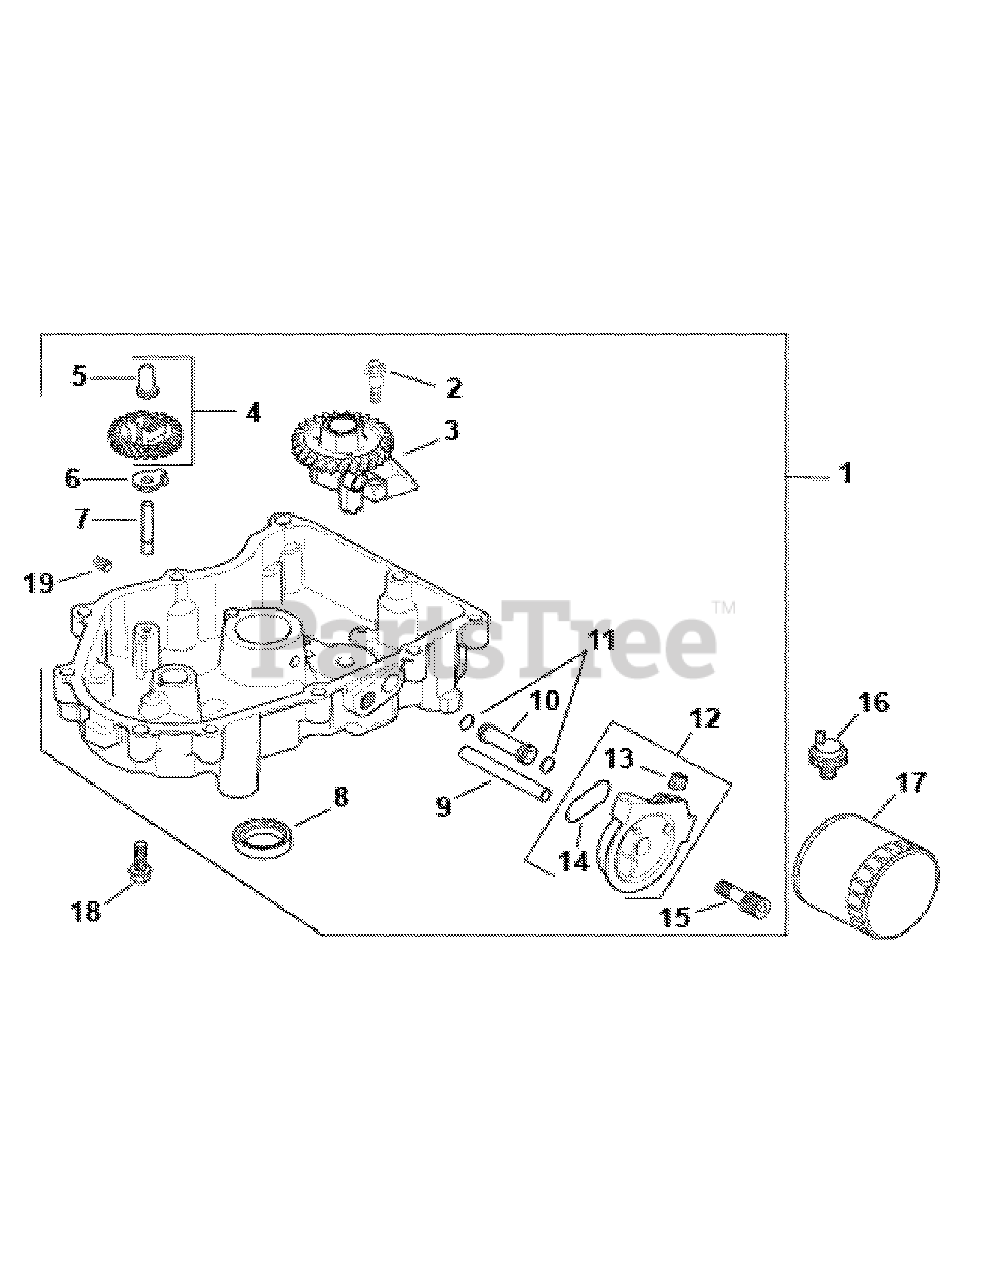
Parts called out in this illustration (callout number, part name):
1	Oil Pan Assembly
2	Shoulder Screw
4	Governor Kit
5	Regulating Governor pin
7	Governor Gear Shaft
8	Oil Seal (PTO End)
9	Oil Feed Tube (Filter To Oil Pan)
10	Oil Feed Tube (Oil Pan To Filter)
12	Oil Filter Adapter Assy.
13	Hex Plug ctsk. 1/8"
15	Oil Filter Nipple
16	Pressure Switch
17	Oil Filter
18	Hex Flange Screw
